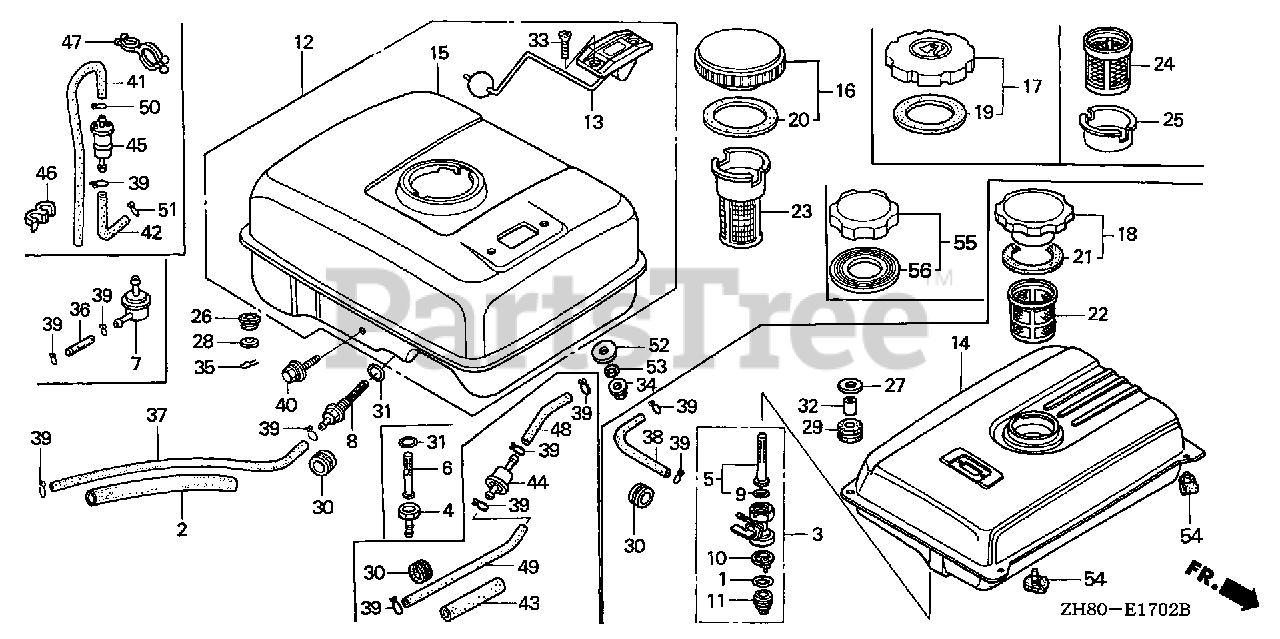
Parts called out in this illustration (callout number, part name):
55	CAP, FUEL FILLER (CHROME PLATED)
55	CAP, FUEL FILLER (CHROME PLATED)(TOUYOUSYA)
56	GASKET, FUEL FILLER CAP (39X62X3) (TOUYOUSYA)
